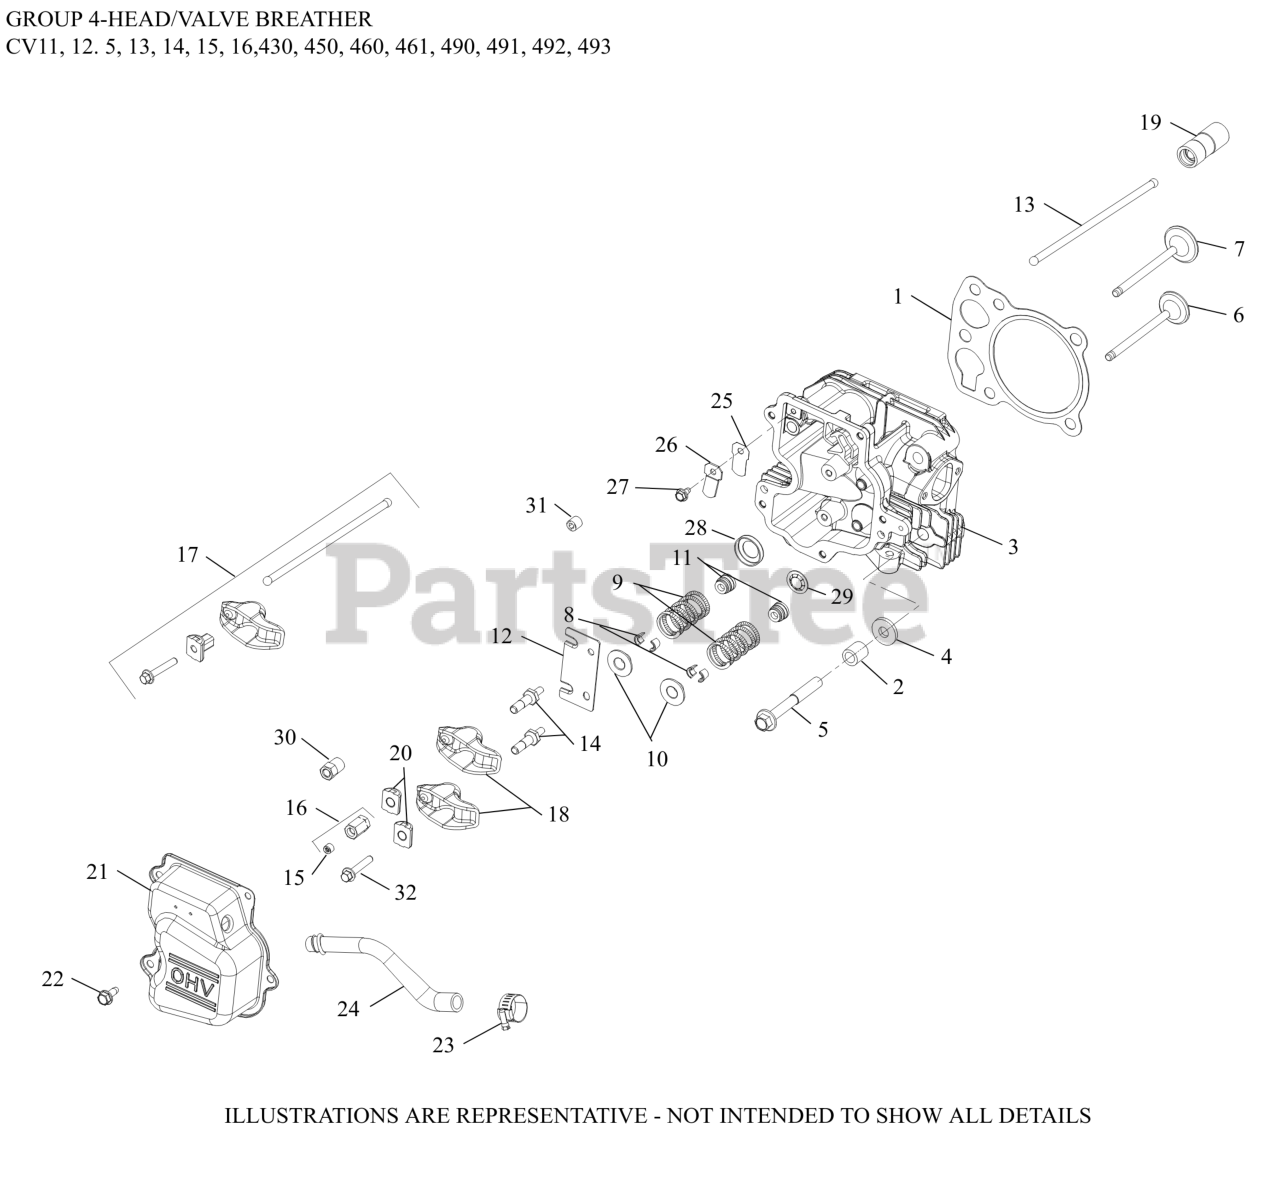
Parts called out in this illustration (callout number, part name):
1	GASKET, CYLINDER HEAD
2	SPACER, HEAD BOLT EXHAUST PORT
3	HEAD ASSY, CYLINDER-DISCONTINUED
4	WASHER, FLAT 13/32"
5	SCREW, CYLINDER HEAD (M10 X 80)
6	VALVE, EXHAUST
6	VALVE, EXHAUST (.25 MM)
7	VALVE, INTAKE
7	VALVE, INTAKE (.25 MM)
8	KIT, RETAINER
9	SPRING, VALVE
10	CAP, VALVE SPRING
11	SEAL, VALVE STEM-USE 25 032 14-S
13	ROD, PUSH-DISCONTINUED
17	KIT, CYL HEAD HARDWARE-(#DSC)
18	ARM, ROCKER
19	LIFTER, VALVE HYDRAULIC-USE 25 351 11-S
20	PIVOT, ROCKER ARM
21	COVER, ROCKER
22	SCREW,FLG THD FRM M6X1.0X16-(#25086397S)
23	CLAMP, HOSE (KM)-USE 25 237 31-S
24	HOSE, BREATHER
25	REED, BREATHER
26	RETAINER, REED
27	SCREW, FLG THD FRM M5X.8X10
32	SCREW, FLG (BLACK) M6X1.0X34
